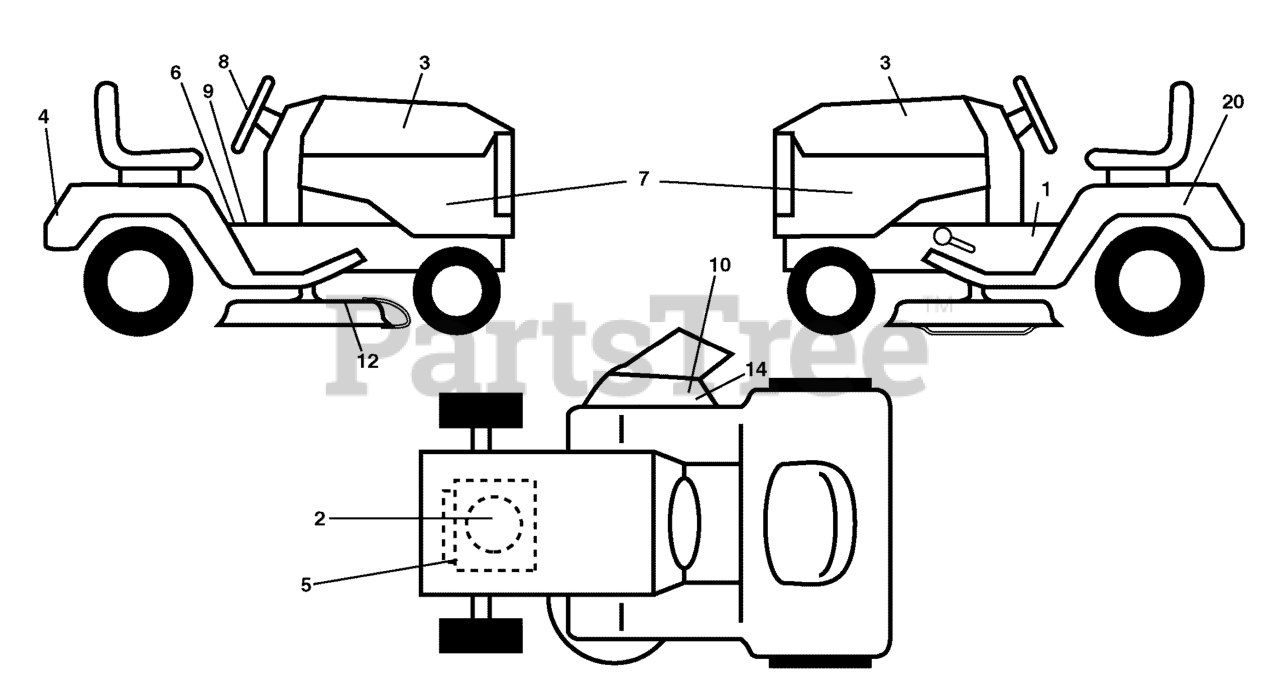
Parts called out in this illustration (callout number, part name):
1	DECAL, Warning Symbols
2	DECAL, Engine HP
3	DECAL, Hood LH/RH
4	DECAL, Fender
5	DECAL, Warning Eng. Symbols
6	DECAL, Brake Clutch
7	DECAL, SDPNL
8	DECAL, Steering
9	DECAL, Saddle Brake Park
10	DECAL, Cutfinger CE
12	DECAL, V-Belt Drive Schematic
14	DECAL, Safety Warning
20	DECAL, Battery Dngr/Psn Eng
